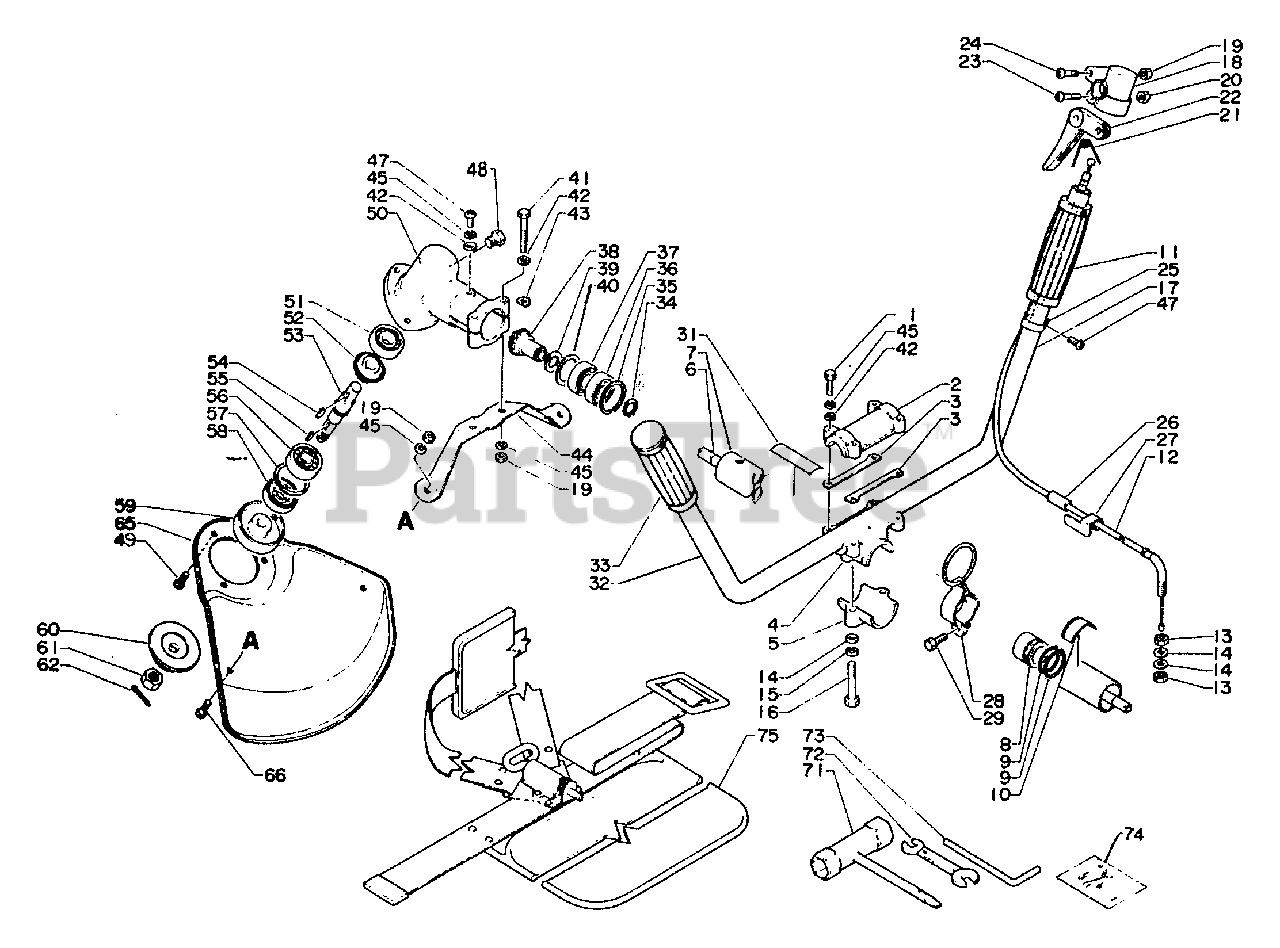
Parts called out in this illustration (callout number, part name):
1	BOLT - 5X25
6	DRIVESHAFT
7	MAIN PIPE ASSY
8	STOPPER
9	O-RING - 22
10	LABEL - ALIGNMENT
11	GRIP, HANDLE
12	CABLE, THROTTLE
14	WASHER - 6
15	LOCKWASHER - 6
16	BOLT - 6X30
18	BRACKET, TRIGGER
19	LOCKNUT - 5
21	SPRING, TRIGGER
22	TRIGGER, THROTTLE
23	SCREW - 5X25
24	SCREW - 5X30
26	TUBE
28	HANGER KIT
29	BOLT - 5X12
31	LABEL - CAUTION
32	HANDLE, FRONT - LEFT
33	GRIP, HANDLE - LEFT
34	RING, RETAINING - 12
35	RING, RETAINING - 28
36	BEARING, BALL - 6001
37	BEARING, BALL - 6001
38	GEAR SET
41	BOLT - 5X40
42	WASHER - 5
44	BRACKET, SHIELD
45	LOCKWASHER - 5
47	SCREW - 5X10
48	BOLT - 8X8
49	SCREW - 5X10
50	CASE, GEAR
51	BEARING, BALL - 6000
52	GEAR SET
53	DRIVESHAFT
56	BEARING, BALL - 6201
57	RING, RETAINING - 32
58	SEAL, OIL
59	ADAPTOR, BLADE - UPPER
60	ADAPTOR, BLADE - LOWER
61	NUT - 10 -- LEFT HAND
62	PIN, SPLIT - 2X22
65	SHIELD, DEBRIS - METAL
66	SCREW - 5X8
71	T-WRENCH
72	SPANNER - 8X10mm
73	LOCKING TOOL
74	PIN, SPLIT - 2X22
75	SHOULDER STRAP ASSY
